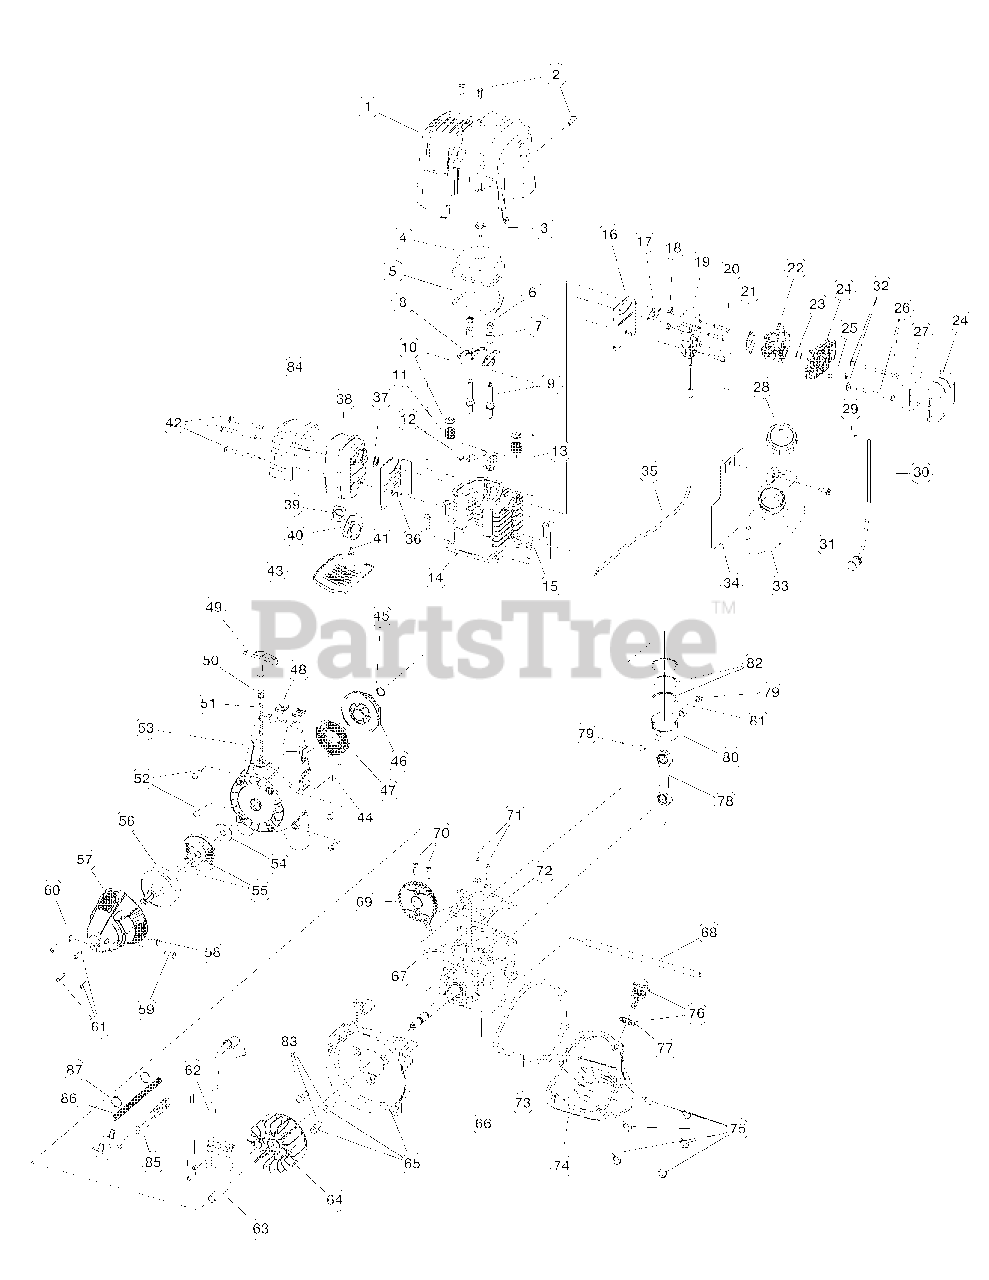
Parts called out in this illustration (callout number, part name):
1	Engine Cover
2	Engine Cover Screws
3	Valve Cover Screw
4	Valve Cover
5	Valve Cover Gasket
6	Rocker Adjustment Nut
7	Rocker Arm Pivot
8	Rocker Arm
9	Rocker Arm Stud
10	Valve Spring Retainer
11	Valve Spring
12	Push Rod Guide
13	Push Rod
14	Cylinder Assembly (Incl. 9, 12, 15, 71 & 72)
15	Cylinder Screw
16	Intake Baffle
17	Carburetor Mount Gasket
18	Nut
19	Carburetor Mount (Incl. 18)
20	Carburetor Mount Screw
21	Carburetor Gasket
22	Carburetor with Primer
23	O-Ring, Carburetor
24	Air Filter Assembly (Incl. 27)
25	Breather Tube
26	Air Filter Mounting Screw
27	Air Filter
28	Fuel Cap
29	Fuel Return Line
30	Fuel Pick-Up Line with Filter
33	Fuel Tank Assembly (Incl. 28-30)
34	Fuel Tank Shield
35	Throttle Cable
36	Muffler Baffle
37	Muffler Gasket
38	Muffler (Incl. 37, 39-41)
39	Spark Arrestor Screen
40	Screen Cover
42	Muffler Mounting Screw
43	Muffler Cover
44	Wire Grommet
45	Pulley Retainer
46	Recoil Pulley
47	Recoil Spring
48	Nut Clip
49	Pull Handle
50	Rope Guide
52	Starter Housing Screw
53	Starter Housing Assembly (Incl. 45-52)
54	Clutch Washer
55	Clutch with Spacer
56	Clutch Drum
57	Clutch Cover
58	Anti-Rotation Screw
59	Screw
61	Clutch Cover Screw
62	Ignition Module Assembly
64	Flywheel
65	Shroud Assembly (Incl. 83)
66	Crankcase Assembly (Incl. 67 & 68)
67	Breather Fitting
68	Breather Hose
69	Cam Bracket Assembly
70	Cam Bracket Screw
71	Valves, Intake and Exhaust
72	Cylinder Gasket
73	Oil Pan Gasket
74	Oil Pan (Incl. 73 & 75)
75	Oil Pan Screw
76	Dipstick Assembly (Incl. 77)
78	Connecting Rod
79	Wrist Pin Button
80	Piston (Incl. 82)
81	Wrist Pin
82	Piston Ring Set
83	Shroud Screw
84	Heat Shield
85	Wire Lead
86	Wire Lead Cover
87	Cable Clamp
